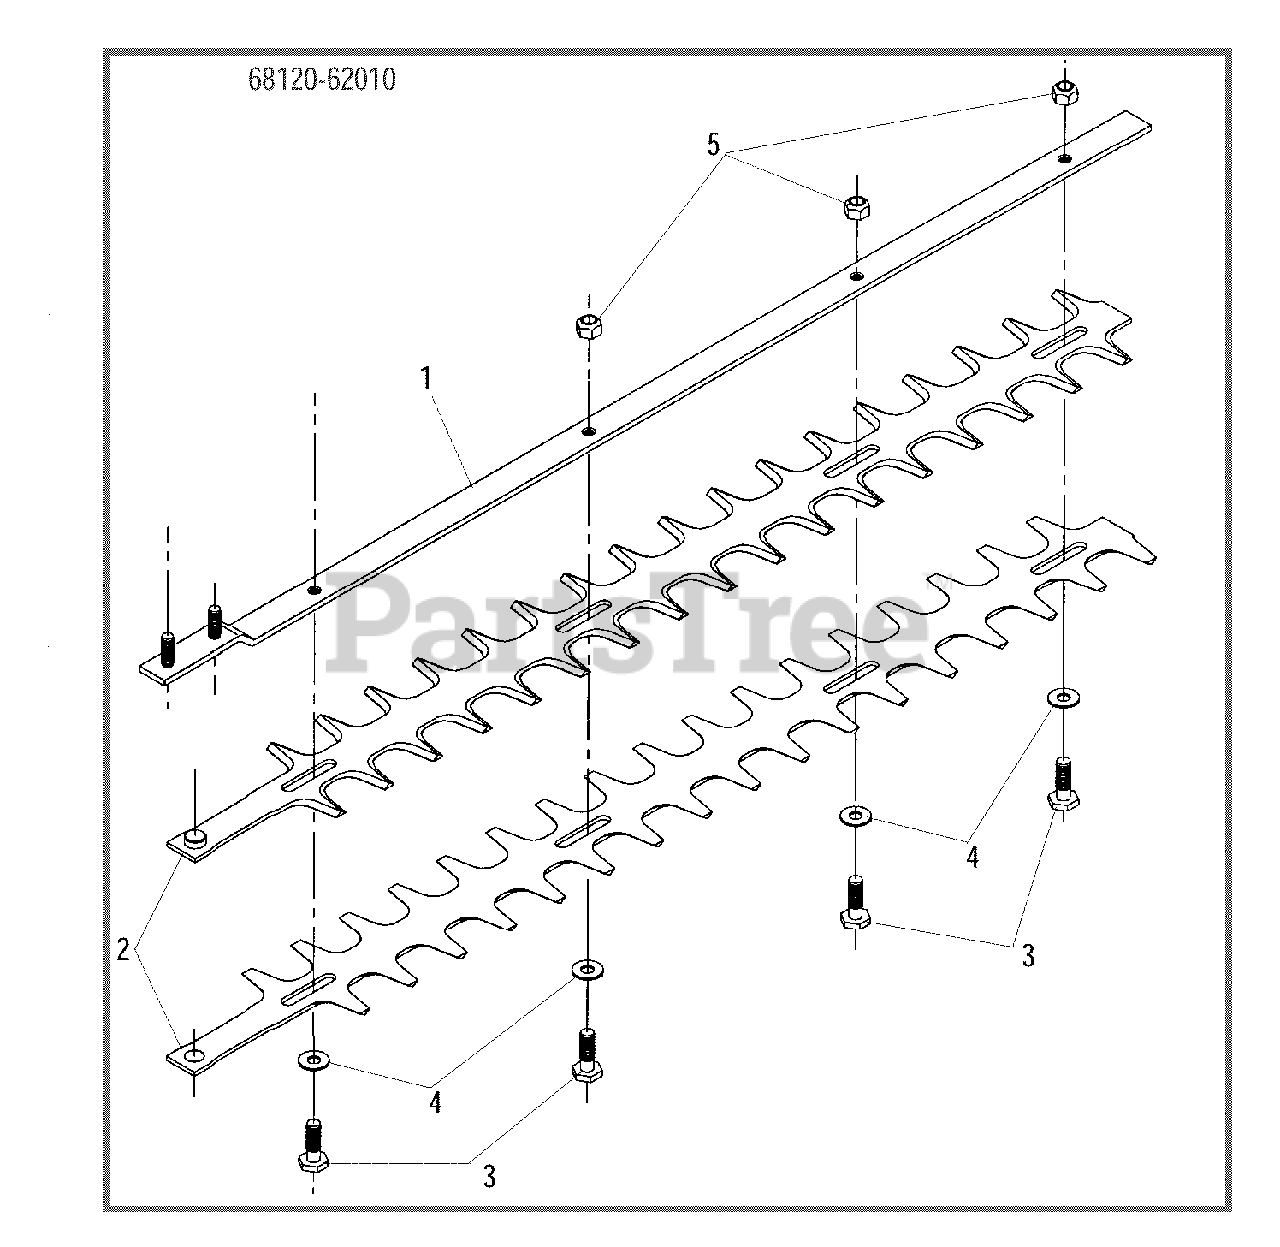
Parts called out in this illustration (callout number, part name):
1	GUIDE BAR - 22" (55cm)
2	BLADE - 22" (55cm)
3	BOLT - 6X20
4	WASHER - 6
5	LOCKNUT
68120-62010	BLADE KIT - 22" (55cm)
